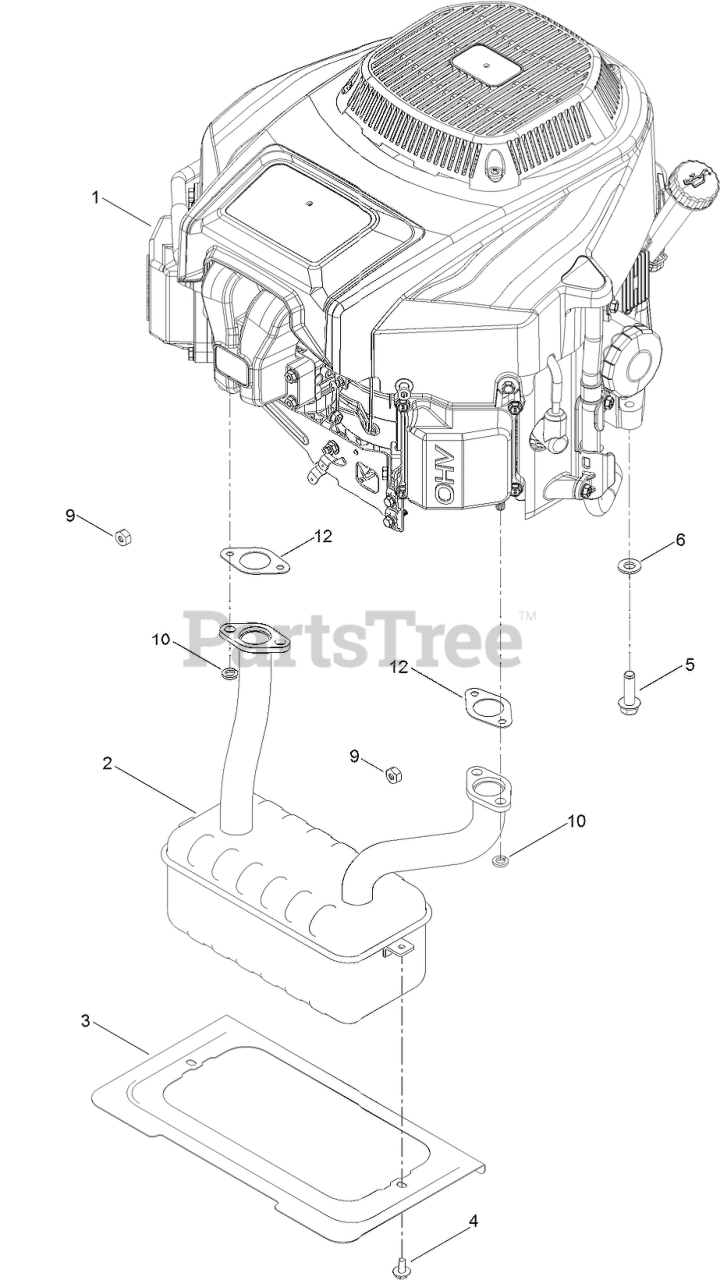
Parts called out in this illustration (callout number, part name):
1	ENGINE-2P77F
2	MUFFLER
3	SHIELD-HEAT
4	SCREW-HHFTF
5	SCREW-THD
6	WASHER-FLAT
9	NUT-HH
10	WASHER-LOCK, SPLIT
12	GASKET-EXHAUST
